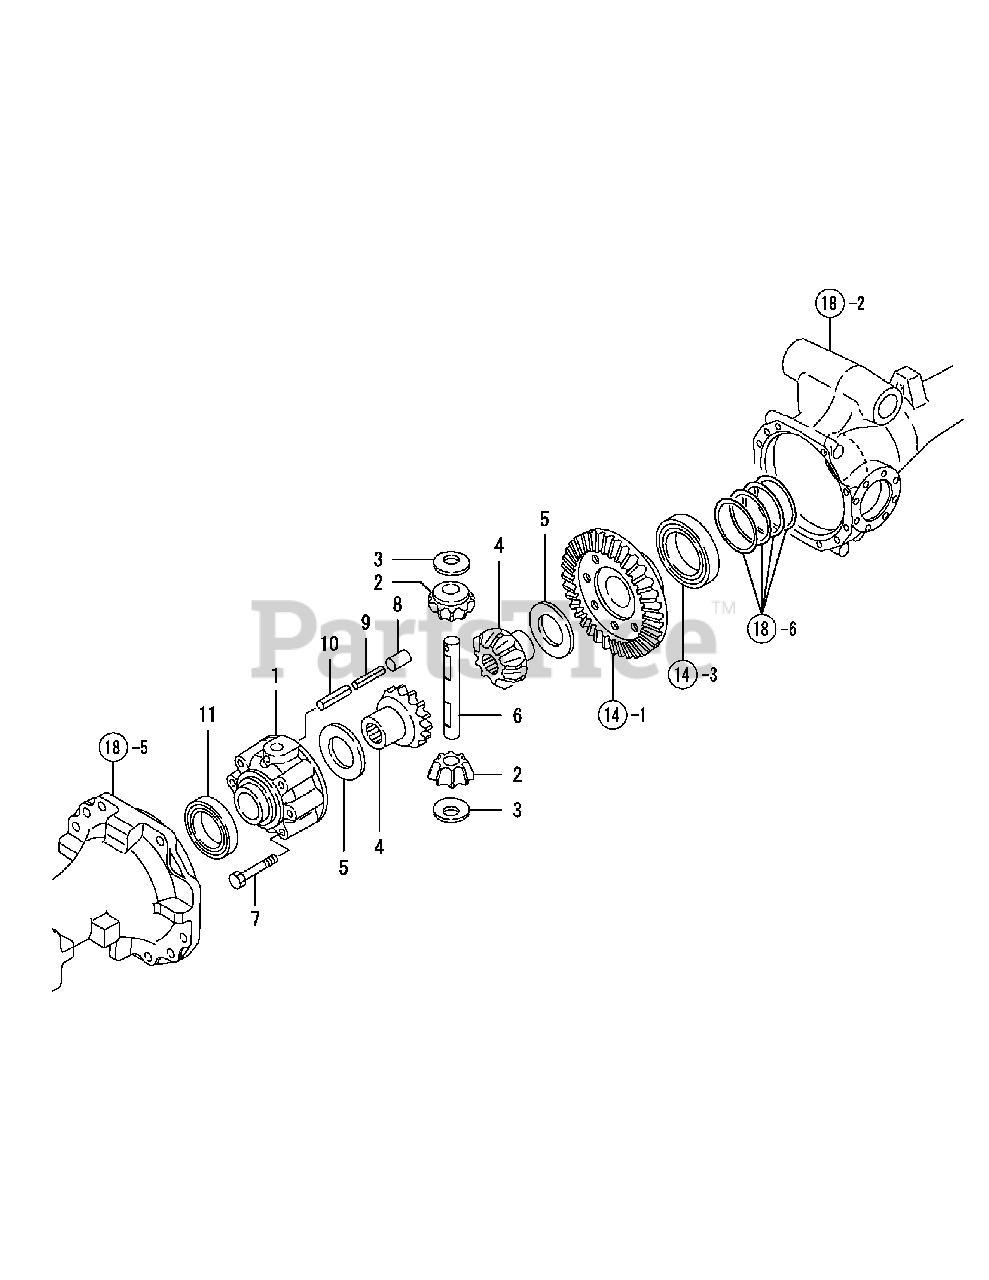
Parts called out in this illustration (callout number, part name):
1	CASE, DIFFERENTIAL
2	PINION, DIFFERENTIAL
3	LINER, DIFFERENTAIL
4	GEAR, DIFF. SIDE
6	SHAFT, DIFF. PINION
8	PARALLEL PIN 10X 18
9	SPRING PIN 3.5X32
10	SPRING PIN 6X32
